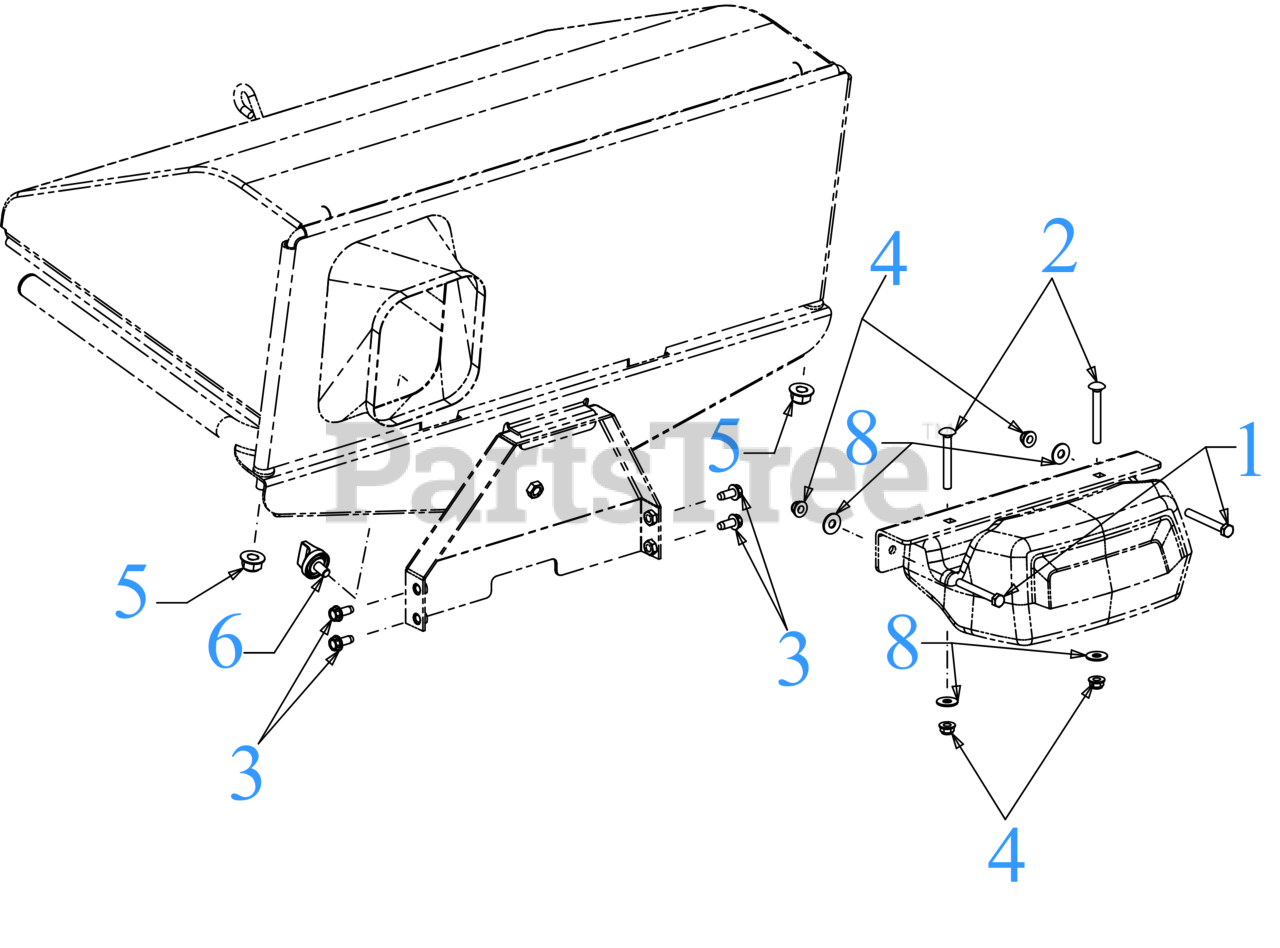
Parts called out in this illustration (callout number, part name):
1	SCREW 5/16-18 x 2.5 GR 5
2	BOLT 5/16-18 x 2.50 GR1
3	SCREW 5/16-18 x .750
4	FLANGE LOCK NUT 5/16-18
6	KNOB 3/8-16 x .625
8	FLAT WASHER
